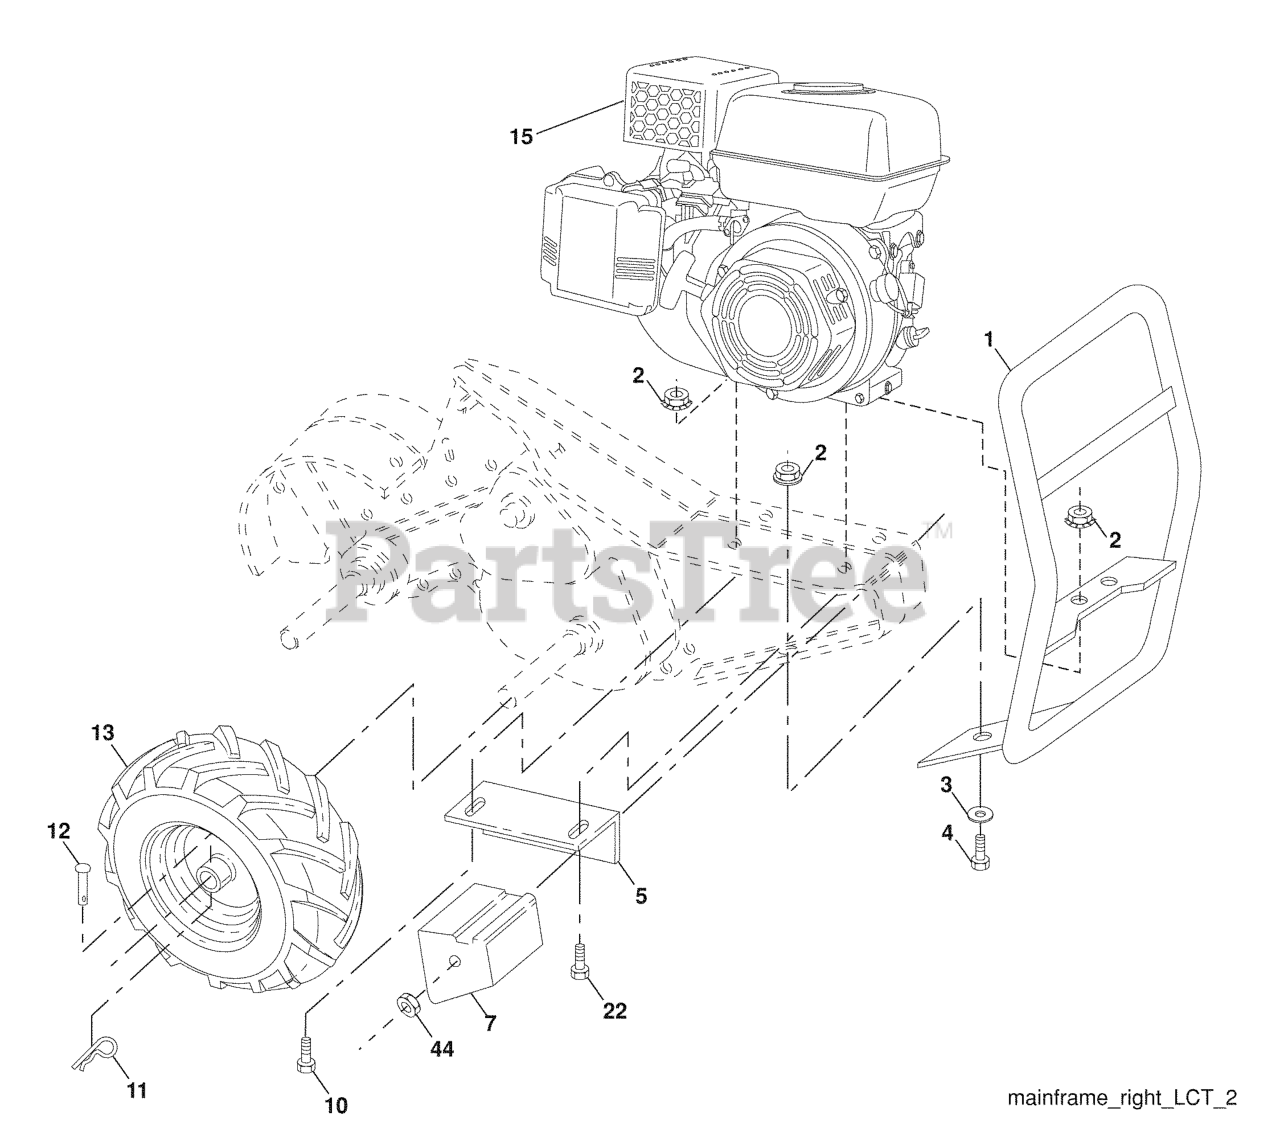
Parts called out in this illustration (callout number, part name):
1	Bumper Asm.
2	Locknut, Hex, Flange 5/16-18
3	Washer 11/32 x 11/16 x 16 Ga.
4	Bolt 5/16-18 x 3/4
5	Bracket, Reinforcement R.H.
7	Counter Weight, R.H.
10	Bolt, Hex 5/16-18 x 1-1/2
11	Clip, Hairpin
12	Rivet, Drilled
22	Bolt 5/16-18 x 1-3/4
44	Nut Keps Hex 3/8-16 unc
